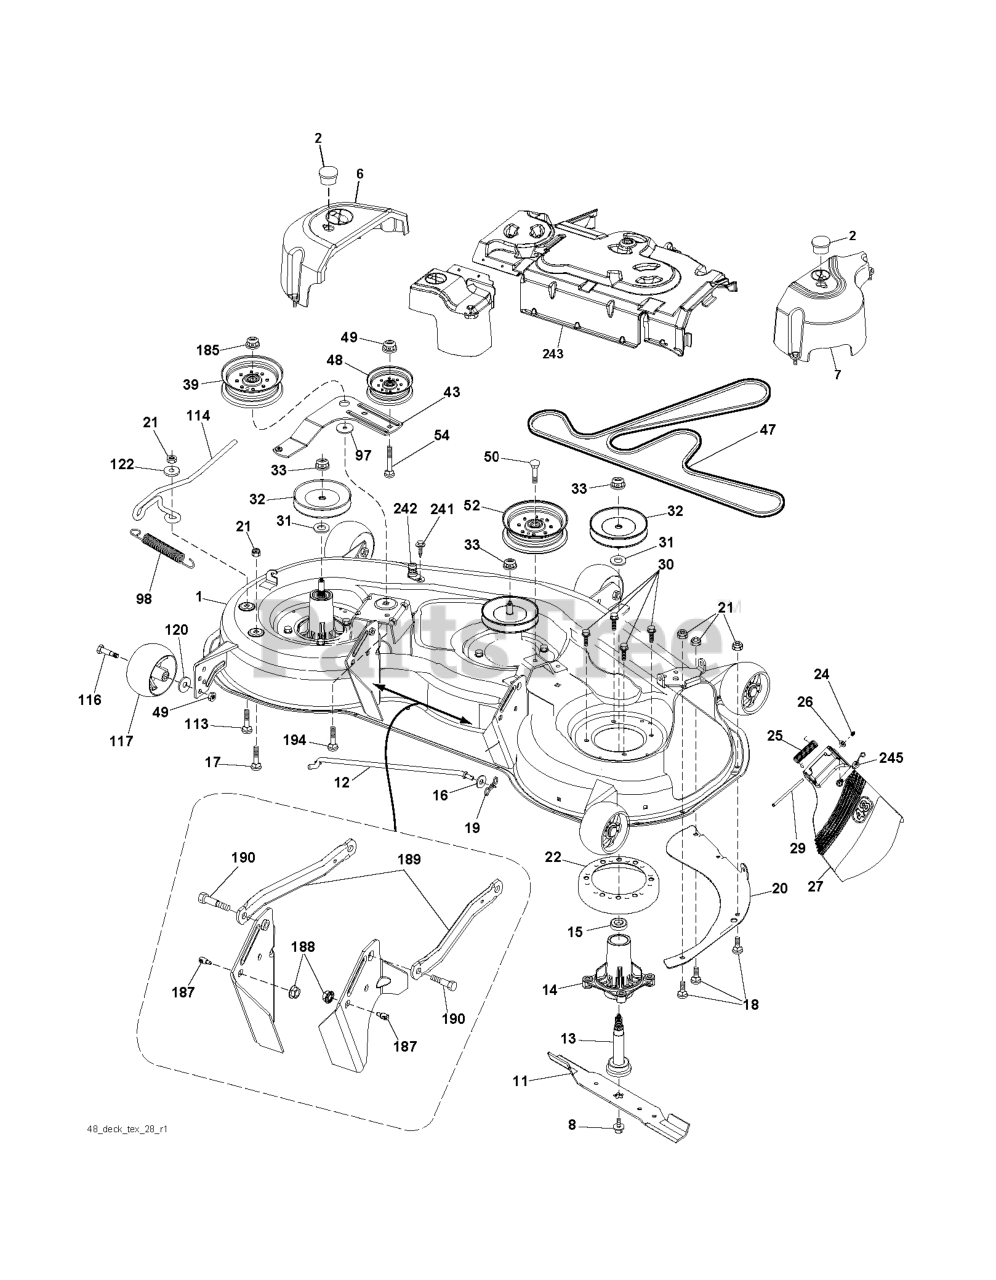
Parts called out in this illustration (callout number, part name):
1	DECK WELDMENT
8	BOLT.WASHER.ASM.7/16-2
11	48" HI-LIFT BLADE
12	ROD.ANTI.SWAY.48/54"K4
13	SHAFT ASM MANDREL
14	RP.HOUSING.MANDREL.4PT.
16	WASHER
17	BOLT.CARR.5/16-18X5/8.SHORT
18	BOLT
19	PIN.COTTER.5/16.BOW TI
20	BAFFLE, VORTEX MWR
21	LOCKNUT
22	STRIPPER.MANDREL.ROUND.BLACK
24	CAP-SLEEVE LT
25	SPRING, TORSION
26	NUT PUSH M
29	ROD.HINGE
30	SCREW, WASHER HEAD
31	WASHER.SPACER.MANDREL
32	PULLEY MANDREL
33	NUT.FLANGE.LOCK.TOP
39	RB PULLEY.IDLER.4.50/HUB SPEC
47	BELT.DRIVE.DECK
48	PULLEY.IDLER.48"PRIMARY
49	NUT LOCK FLG 3/8-16 UNC
50	SCREW TT 3/8-16X2-1/4 UNC
52	PULLEY.IDLER.2006
54	BOLT.3/8-16X1.50
98	SPRING, DECK DRIVE
114	ROD.TENSION.RELIEF.TEX (2 2)
116	BOLT.SHOULDER.3/8-16X3-5/8.
117	RP WHEEL. GUAGE RALLY
120	WASHER
122	BUSHING.RELIEF.TENSION
185	NUT.LOCK.FLANGE.7/16
187	STUD.FASTNER.W/ANTI-ROTATE
188	NUT LOCK HEX FLANGE 5/16-18
189	ARM.SUSPENSION.MOWER
190	BOLT.SHOULDER
194	BOLT.CARR.SQNK.7/16
241	SCREW.TT.#10-32X.5.3/8.FLANGE
242	PORT.WASHOUT
245	ELASTIC STRAP KIT
